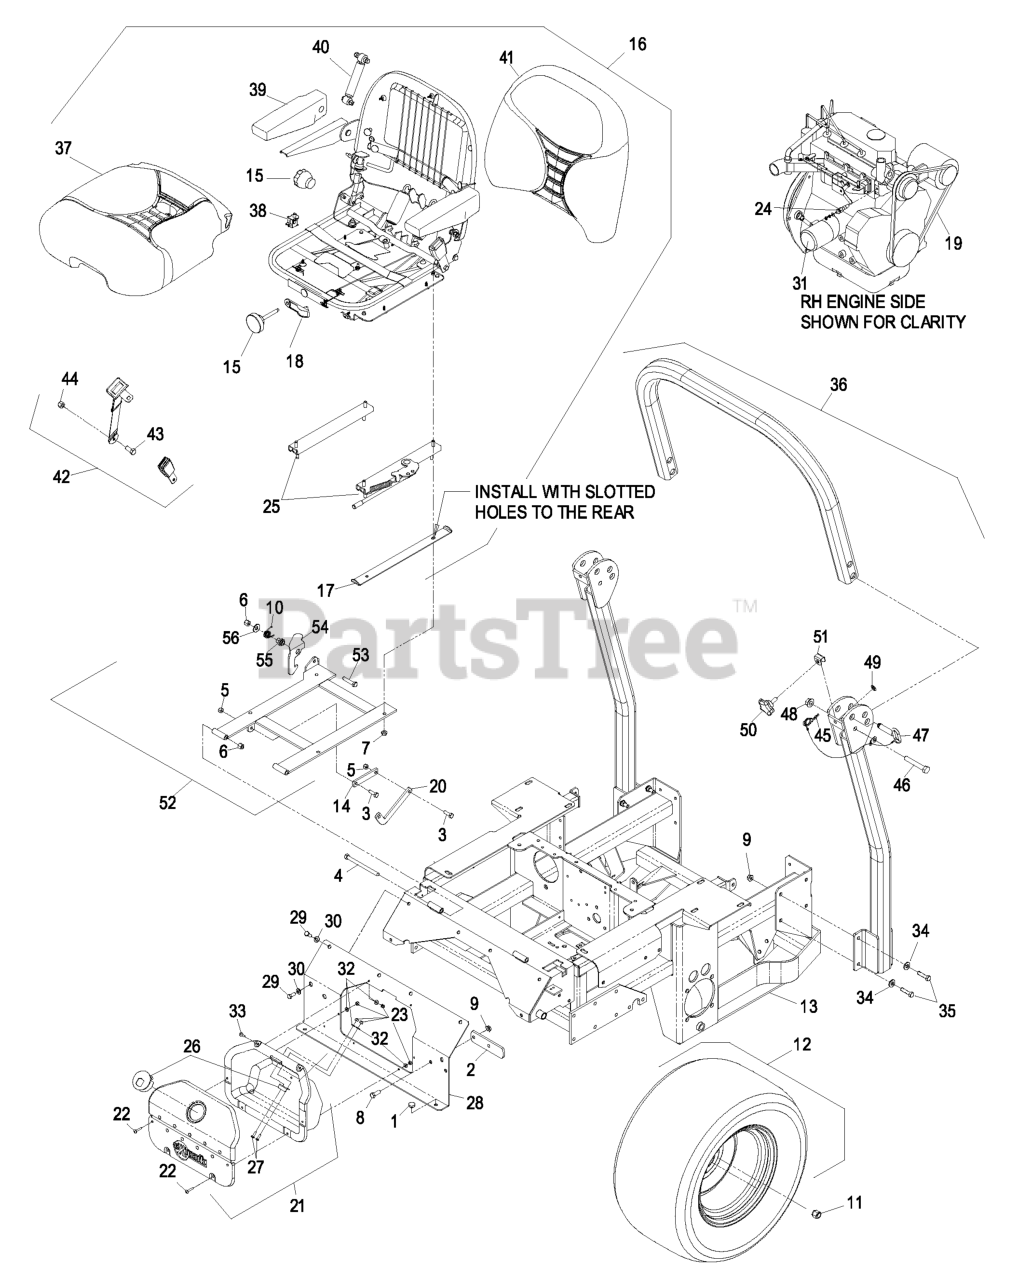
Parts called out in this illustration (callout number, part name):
2	STOP-BRAKE, PARK
3	SCREW-HH
4	SCREW-HH
5	NUT-LOCK, NI
6	NUT-LOCK, NI
8	SCREW-HH
9	NUT-HHF, WHIZ
10	SPRING-TORSION, LATCH
11	NUT-LUG
13	KIT,XP ENG DECK W/DECALS
14	LINK-STOP, SEAT
15	KNOB KIT
17	STOP-SEAT
18	WEIGHT INDICATOR KIT
19	Briggs & Stratton P/N 821075 Engine V-Belt
20	LINK-SEAT STOP, LOWER
21	ASM,CUBBY
23	NUT-LOCK, NI
24	SENDER-TEMPERATURE
25	SEAT TRACK KIT
26	LATCH,CUBBY
27	SCREW-PPH
29	SCREW-HH
30	WASHER-PLAIN
31	Briggs & Stratton P/N 820314 Oil Filter
32	WASHER-FLAT
33	SCREW-HEAD, TRUSS
34	WASHER-BELLEVILLE
35	SCREW-HH
37	BOTTOM CUSHION KIT
39	PAD-ARMREST
40	SHOCK ABSORBER KIT
41	BACK CUSHION KIT
42	SEATBELT KIT
43	SCREW-HH
44	NUT-LOCK, NI
45	HAIRPIN
46	SCREW-HH
47	PIN-FOLD, ROPS
49	NUT-PUSH
53	SCREW-HH
54	CATCH-LATCH, SINGLE
55	BUSHING-LATCH, SEAT
56	WASHER-FLAT
